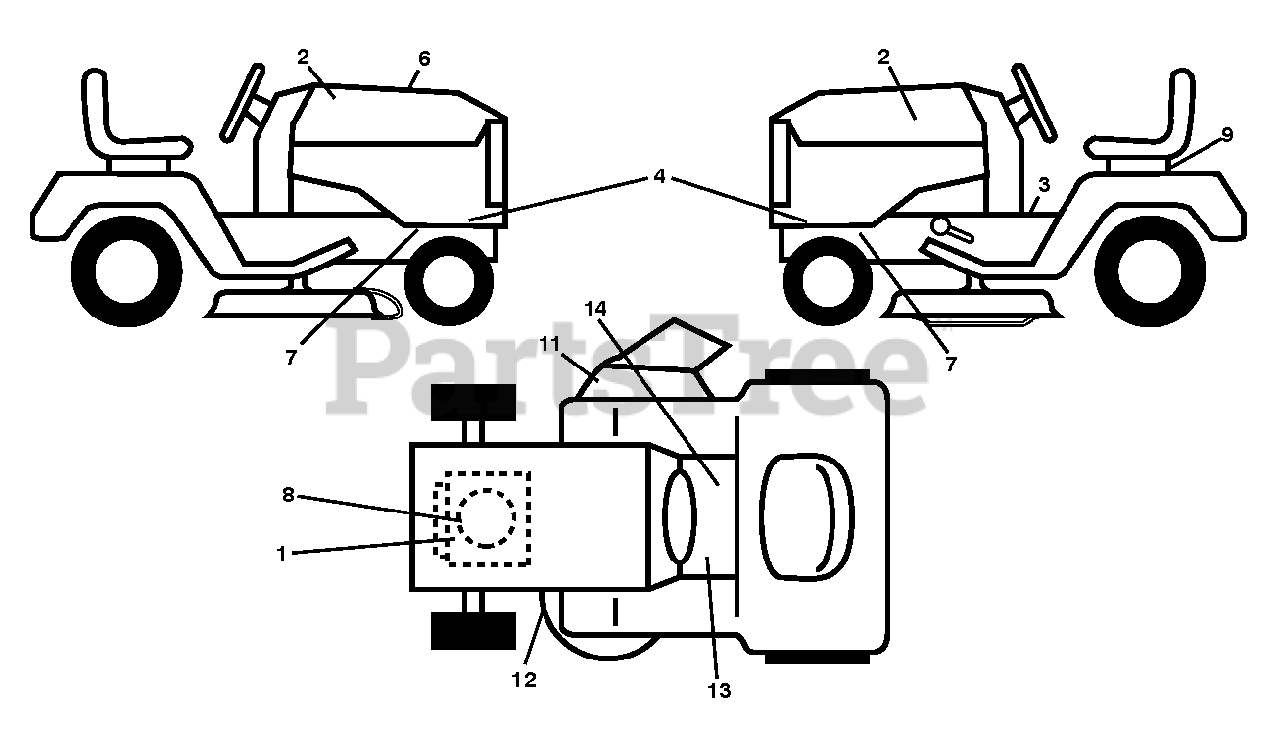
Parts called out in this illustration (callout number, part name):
1	DECAL.ENGINE.WARNING
2	DECAL.BADGE.170MM.TEXTLOGO.
3	DECAL.READ.OWN.MAN.SYMBOL.LT
7	DECAL.CHASSIS.HOT.MUFFLER
8	DECAL
9	DECAL BTRY SYMBOLS
11	DECAL.WARN.DFLCTR/CTFNGR.SRD.
12	DECAL.V.BELT.30"
13	DECAL.FNDR.SDLE.BRAKE.CLUTCH.6
14	DECAL.PARKING.BRAKE.SADDLE.LT
